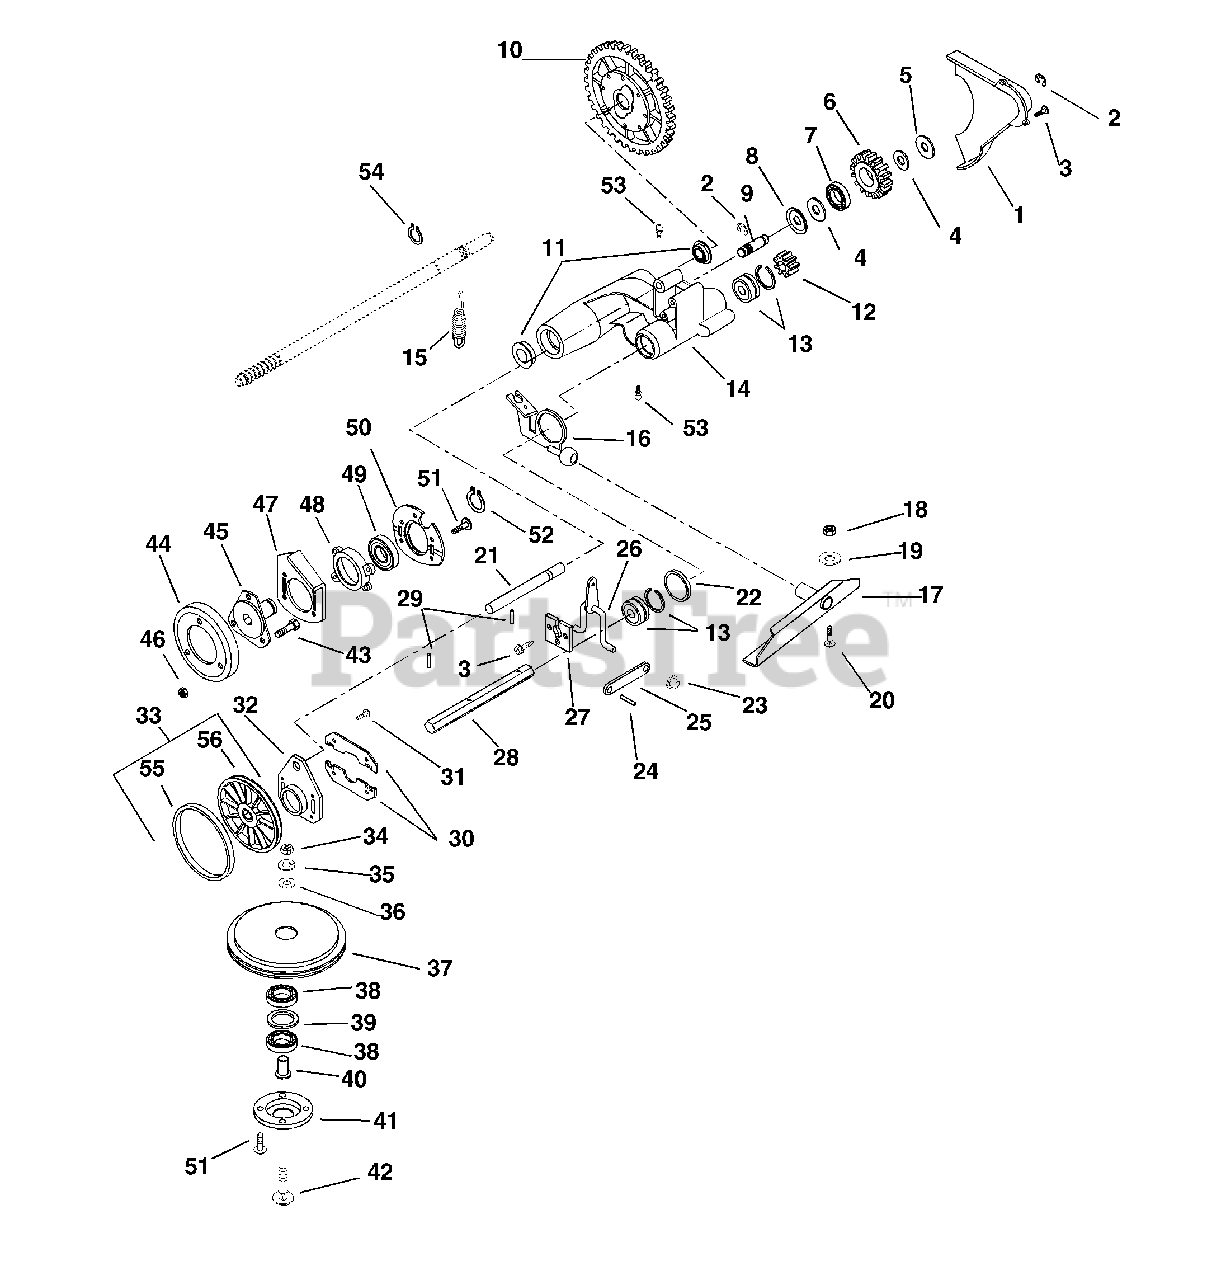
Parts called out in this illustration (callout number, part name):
1	COVER, GEAR
2	RG-RTNG-EXT .438X.035
3	@SCR-TAP 12-24X.50 HWH TR YWZC
4	WSHR-FL-STL .52X.827X.062 YWZC
5	WSHR-FL-STL.531X1.00X.063 YWZC
6	IDLER GEAR
7	BRG-BALL .500X1.38X.437
8	RETAINER
9	IDLER SHAFT
10	DIFFERENTIAL ASSEMBLY
11	BRG-BALL .625X1.383X.50
13	BRG-BALL .562X1.375X.437
14	DRIVE MOUNT
15	SG-TENS .051X.60X2.25 WLD 7.0
16	DRIVE ACTUATOR WELDMENT
17	PIVOT CHANNEL WELDMENT
18	@NUT-LK-CTR .31-18 YWZC
19	@WSHR-FL-STL.344X.688X.065YWZC
20	@BLT-RHDSSQNK .31-18X.62 G5YZ
21	ROD - GUIDE
22	WSHR-FL-STL 1.390X2.00X.020 PL
23	PUSH NUT, .25
24	PIN-ROLL .125X.50
25	SHIFT LINK
26	SHIFT ARM WELDMENT
27	RETAINER PLATE
28	HEX SHAFT
29	PIN-ROLL .188X.88
30	THRUST PLATE
31	@SCR-TAP 10-24X.375 HWH YZ TR
32	GUIDE PLATE
33	FRICTION WHEEL ASSEMBLY
34	@NUT-HEX .31-18 YWZC
35	WSHR-LK .312X.097 HVY YWZC
36	WSHR-FL-STL .328X.875X.062YWZC
37	FRICTION SHEAVE
38	BRG-BALL .625X1.375X.43
39	WSHR-FL-STL 1.062X1.344X.032PL
40	SPINDLE - BEARING
41	RETAINER - BEARING
42	@BLT-RDHDSQNK .31-18X1.75 G5YZ
43	@BLT-HEX .25-20X.50 GR5 YWZC
44	FRICTION DISC
45	FRICTION WHEEL HUB
46	@NUT-LK-CTR .25-20 YWZC
47	BEARING PLATE
48	BEARING RETAINER
49	BRG-BALL 1.0X2.0X.56 (1641)
50	BEARING RETAINER
51	@SCR-TAP 12-24X.50 HWH TR YWZC
52	RG-RTNG-EXT 1.00X.042
53	FTG-LUBE .25-28X.256 YWZC
54	RG-RTNG-EXT .625X.035
55	FRICTION RING
56	FRICTION WHEEL HUB
